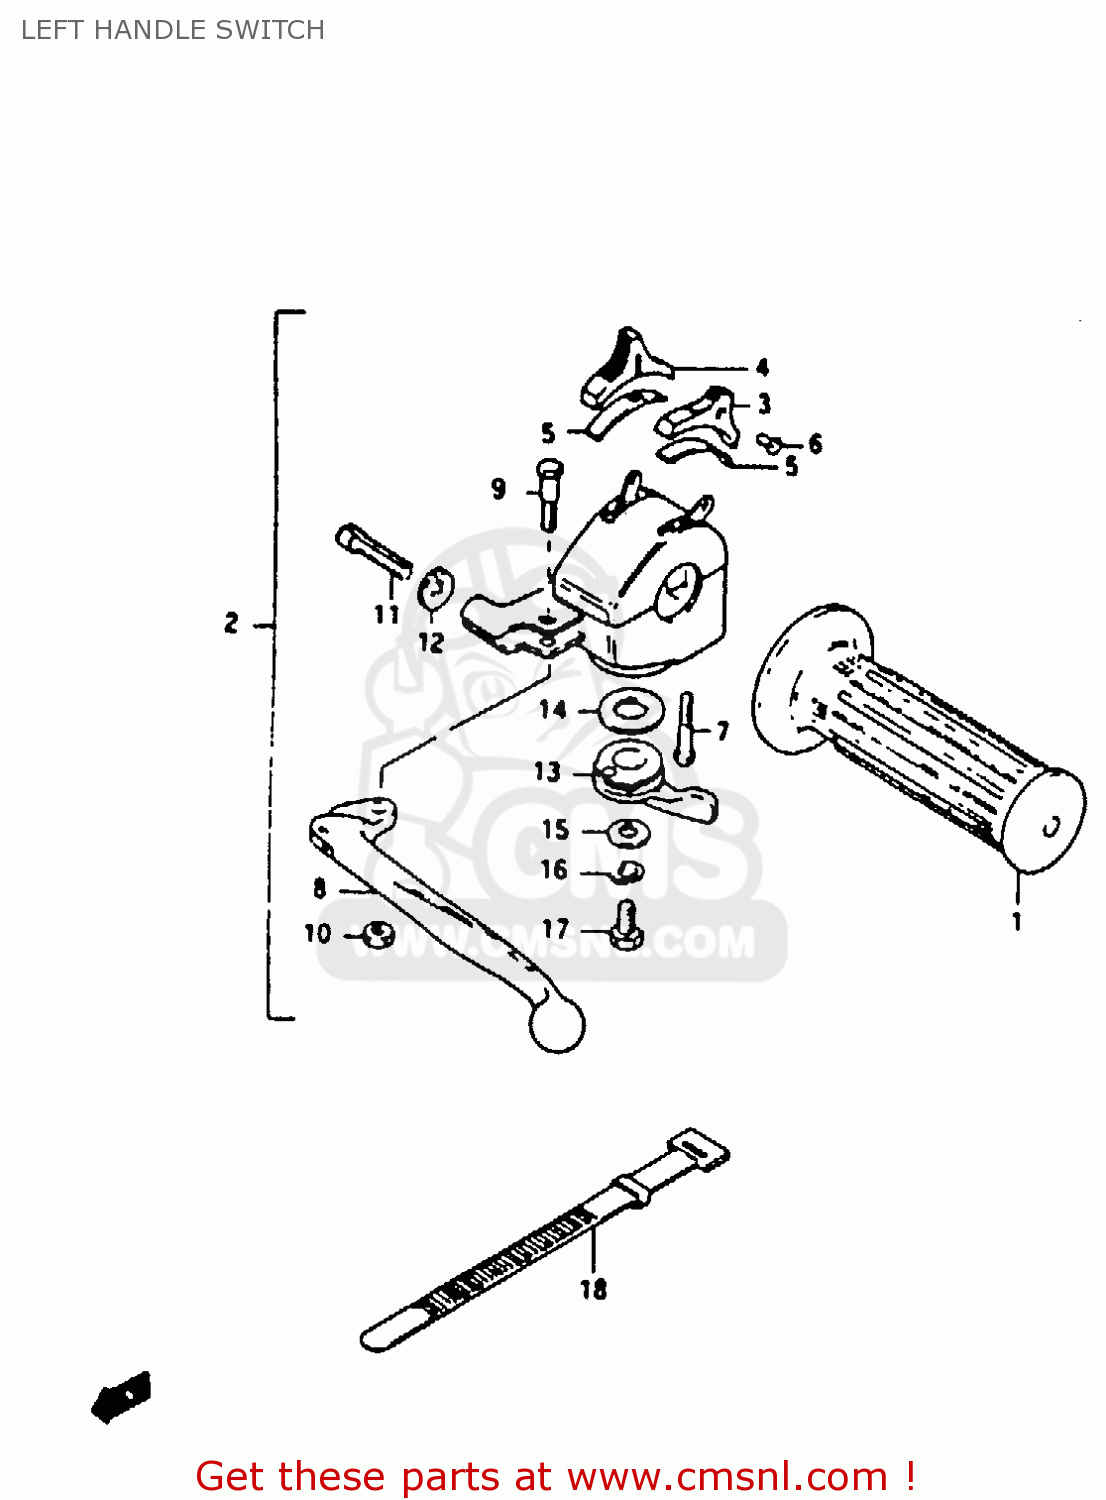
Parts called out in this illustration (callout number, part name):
1	GRIP,L
2	LEVER ASSY,CLUTCH
3	KNOB,HANDLE SWITCH
4	KNOB
5	PLATE,SWITCH KNOB
6	SCREW
7	SCREW 5X20
8	LEVER,CLUTCH
9	BOLT,LEVER PIVOT
10	NUT 6MM
11	ADJUSTER,CABLE
12	NUT,CABLE ADJUSTER
13	LEVER,STARTER
14	WASHER,ADJUSTER
15	WASHER,STARTER LEVER
16	WASHER,LOCK
17	BOLT
18	CLAMP(L:120)
